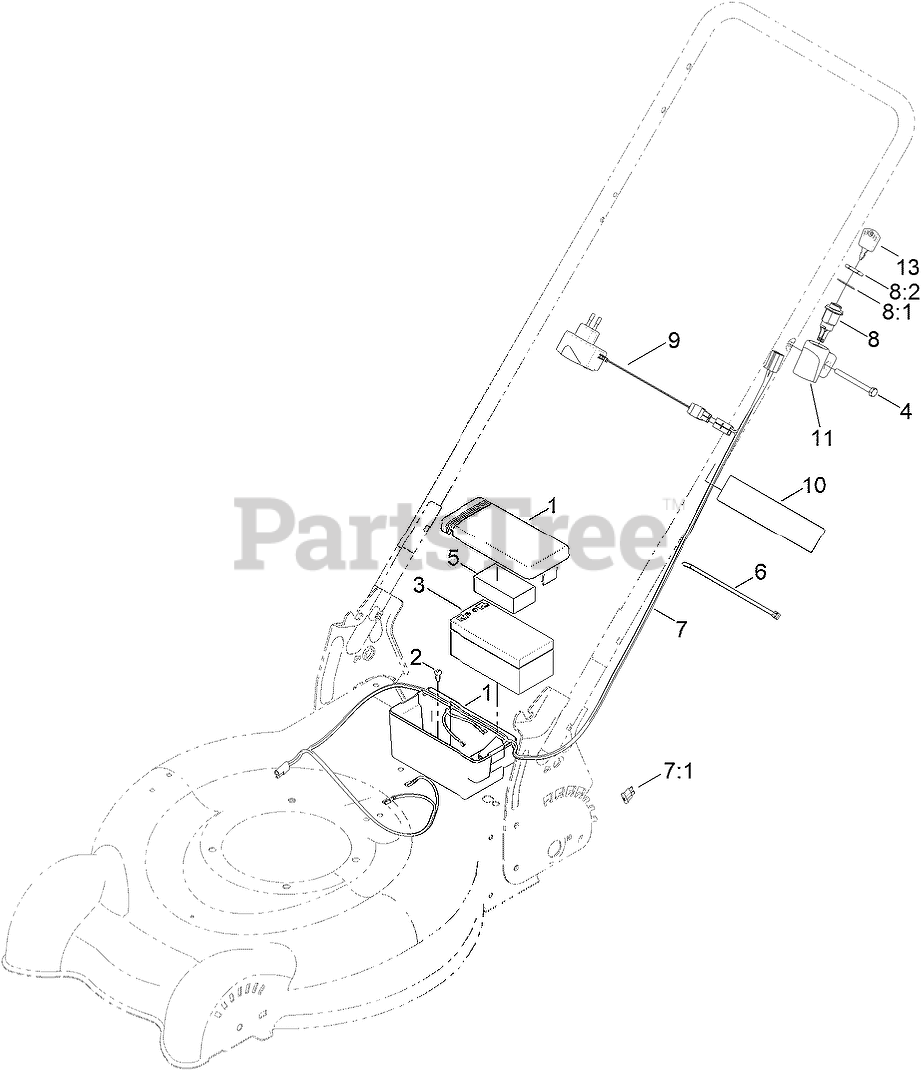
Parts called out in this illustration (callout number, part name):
1	BATTERY BOX ASM
2	SCREW-FORMING, THREAD
3	BATTERY-WET
4	SCREW-HH
5	FOAM-BATTERY, TOP
6	TIE-CABLE
7	HARNESS-WIRE
7:1	FUSE-40 AMP
8	STARTER SWITCH ASM
8:1	WASHER-TOOTH, INTERNAL
8:2	NUT-HH
9	CHARGER-CE
10	DECAL-WARNING
11	MOUNT-SWITCH
